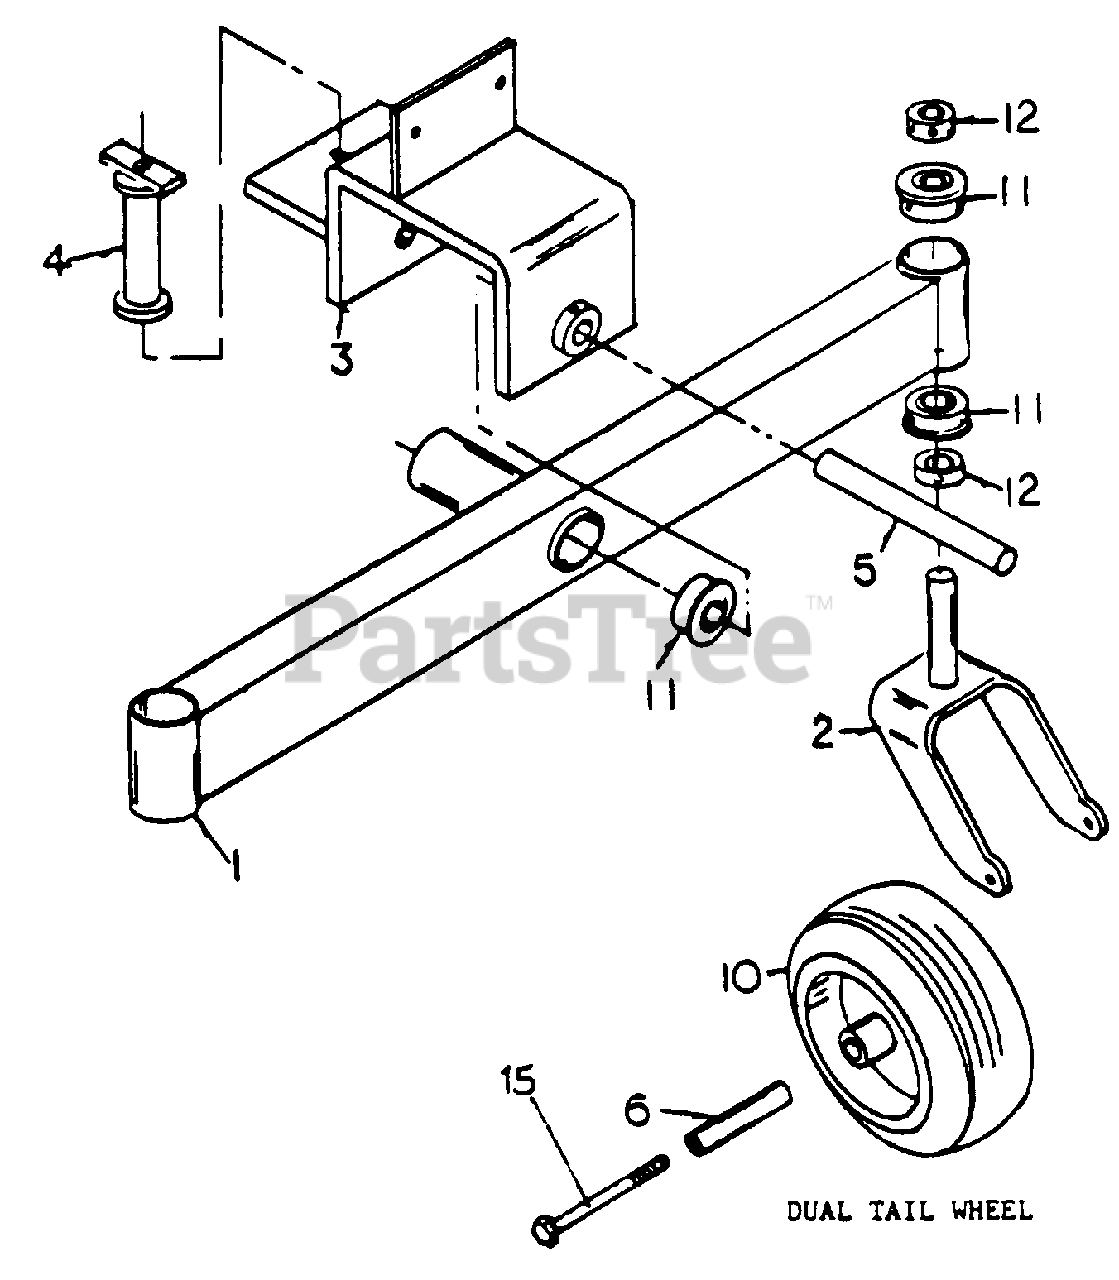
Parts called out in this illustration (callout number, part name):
1	Dual Tail Wheel Axle
2	Dual Tail Wheel Fork
3	Dual Tail Wheel Mbunt
4	Dual Tail Wheel Tube Block
6	Tall Wheel Axle
10	Tail Wheel Assembly
12	Set Collar, 1"
15	Hex Cap Screw, 1/2-13 x 6 1/2"
